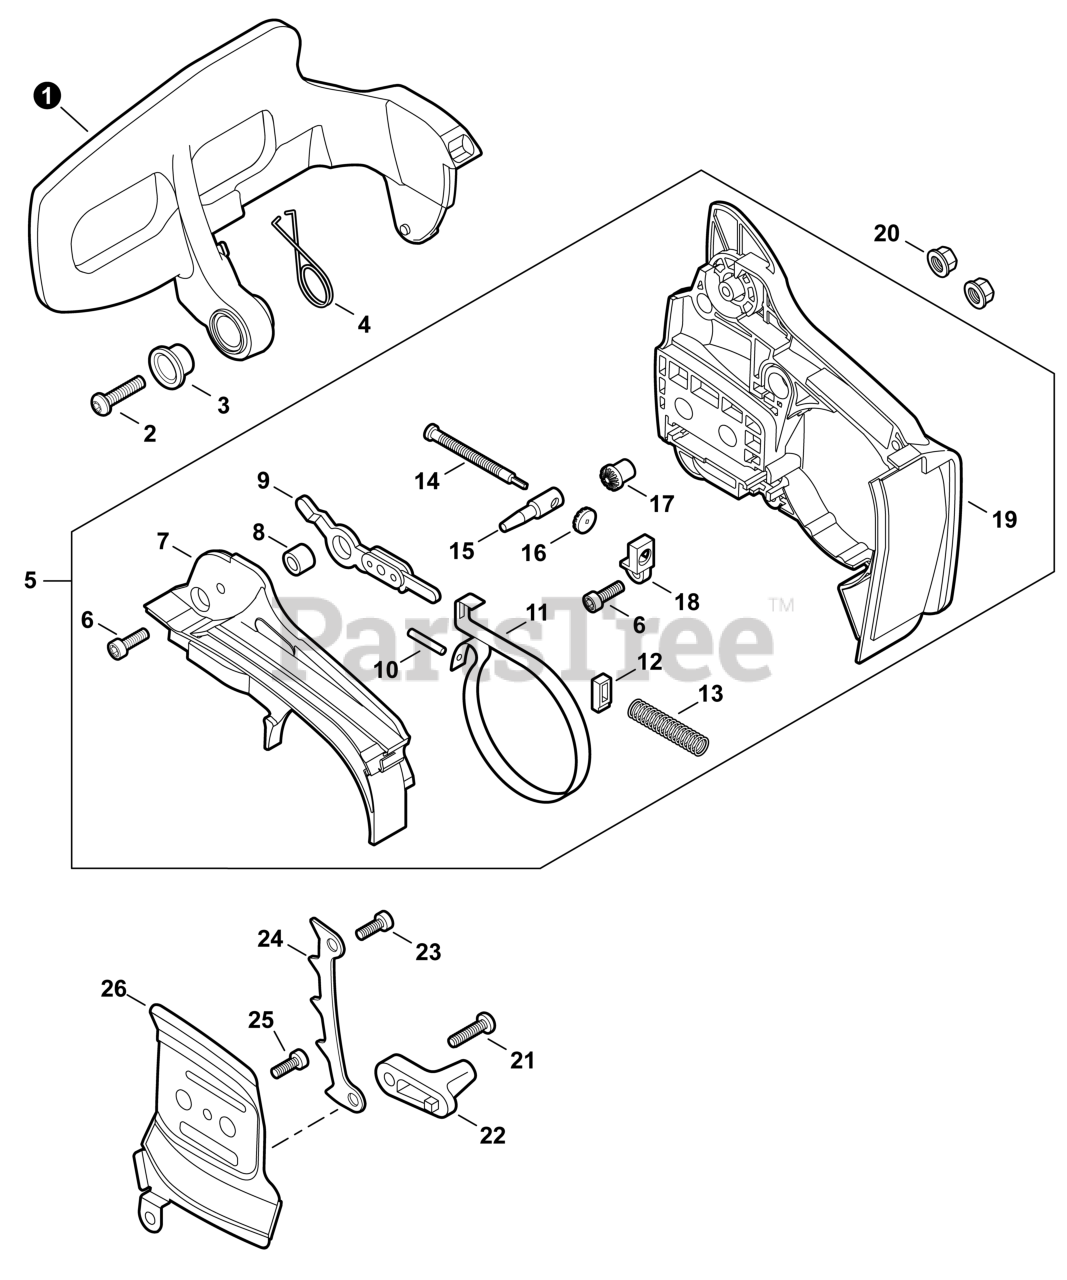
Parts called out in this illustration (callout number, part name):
1	LEVER, BRAKE
2	BOLT, TORX 5x12
3	COLLAR 10
4	SPRING, TORSION
5	SPROCKET GUARD ASSY
6	BOLT, TORX 4x12
7	COVER, BRAKE
8	SPACER 8x12x9
9	CONNECTOR, BRAKE
10	PIN, SPRING 3x9.8
11	BAND, BRAKE
13	SPRING, COMPRESSION
15	TENSIONER, CHAIN
16	GEAR, BEVEL
17	GEAR, BEVEL
18	COLLAR 8
19	GUARD, SPROCKET
20	NUT, FLANGE M8x1.25
21	BOLT, TORX 5x20
22	CATCHER, CHAIN
23	BOLT, TORX 5x20
24	SPIKE, BUMPER
25	BOLT, TORX 4x12
26	PLATE, GUIDE - INNER
